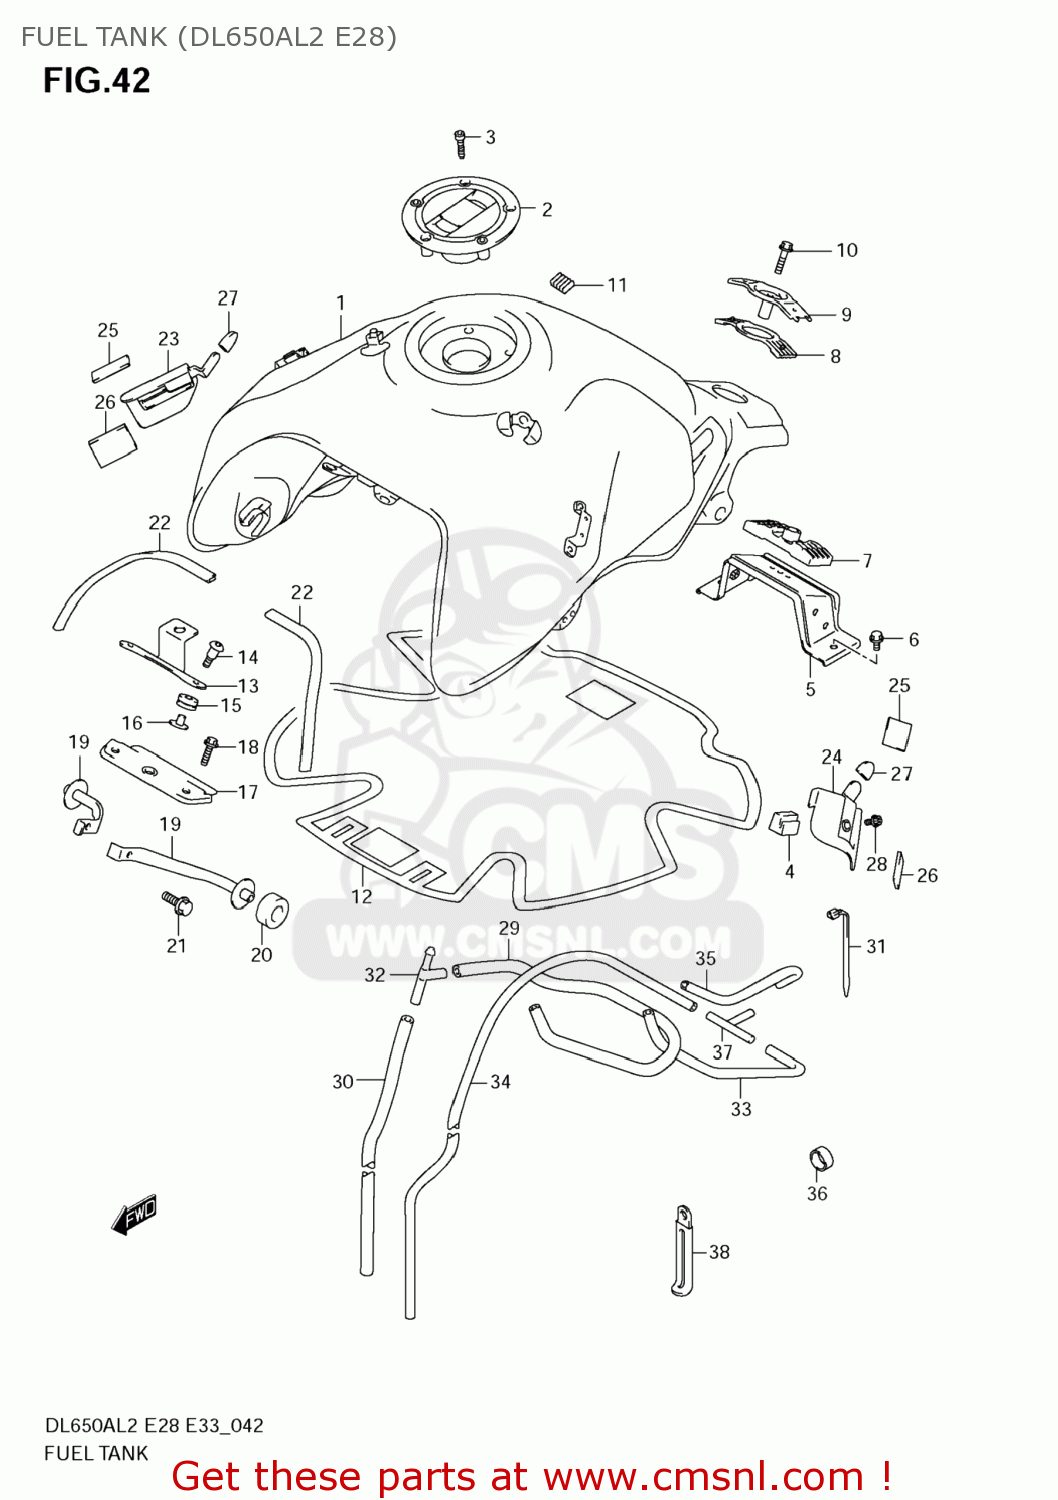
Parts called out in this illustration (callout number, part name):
1	TANK ASSY,FUEL(BLACK)
2	CAP SET,FUEL TANK
3	BOLT,FUEL TANK FILLER CAP
4	CUSHION,FUEL TANK SIDE
5	BRACKET,FUEL TANK RR
6	BOLT
7	CUSHION,FUEL TANK RR LWR
8	CUSHION,FUEL TANK RR UPR
9	BRACKET,FUEL TANK RR UP
10	BOLT
11	FASTENER
12	SHIELD,FUEL TANK CTR
13	BRACKET,FR COVER
14	SCREW(6X25)
15	CUSHION,FUEL TANK FR
16	SPACER,FUEL TANK FR
17	BRACKET,FUEL TANK FR
18	BOLT
19	BRACKET,FR SIDE
20	CUSHION,FR SIDE BRKT
21	BOLT
22	MOLDING,FUEL T
23	BRACKET,FUEL TANK COVER,R
24	BRACKET,FUEL TANK COVER,L
25	FASTENER
26	CUSHION,TANK SIDE COVER
27	CUSHION
28	BOLT
29	HOSE,FUEL TANK DRAIN NO.1
30	HOSE,FUEL TANK DRAIN NO.2
31	CLAMP(L:165)
32	3 WAY
33	HOSE,FUEL TANK BREATHER NO.1
34	HOSE,FUEL TANK BREATHER NO.2
35	HOSE,VACUUM
36	HOSE(12X16X600)
37	3 WAY
38	CLAMP(L:80)
